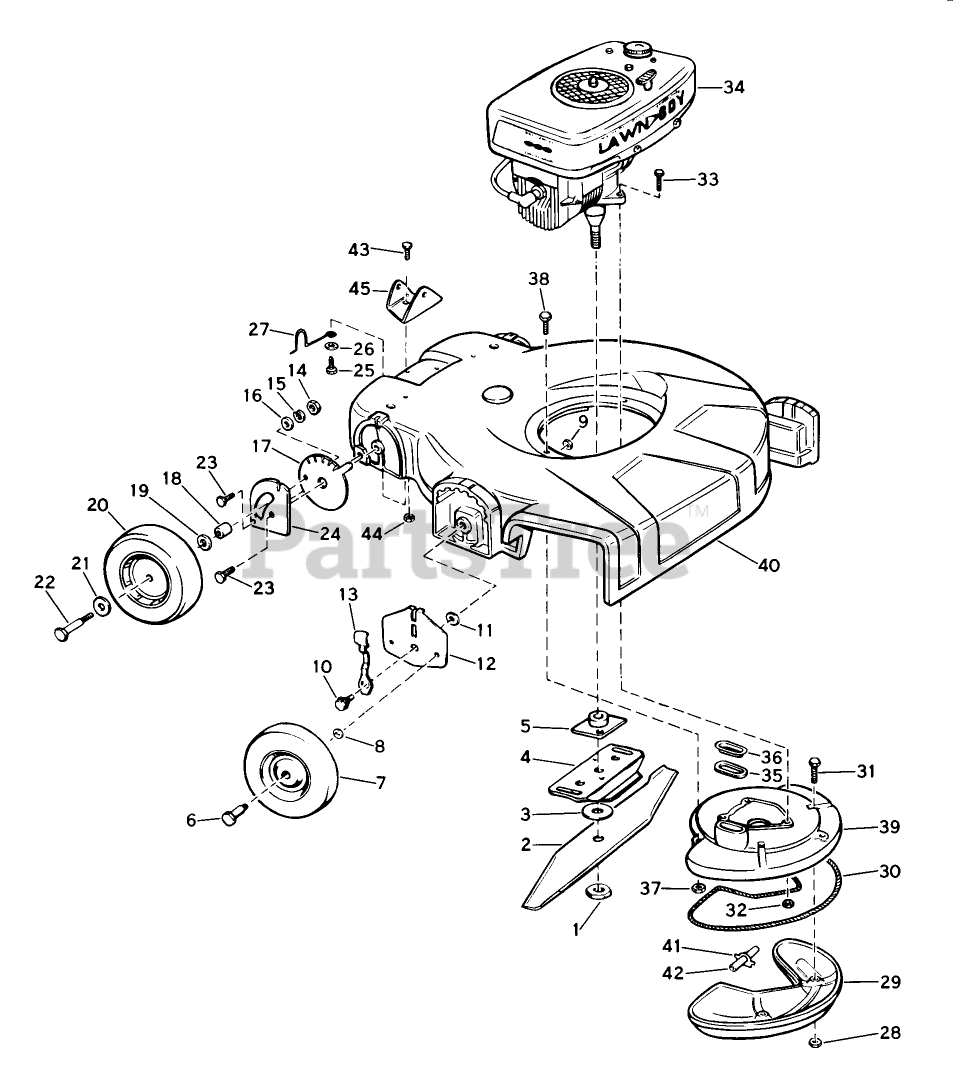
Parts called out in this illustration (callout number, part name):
1	NUT-BLADE
5	PLATE AND COLLAR ASM
6	BOLT WHEEL
8	WASHER WROUGHT
14	Nut-Hex
15	WASHER, LOCK
17	Lever-Wheel
18	Spacer-Wheel
22	Bolt-Wheel
24	Plate-Wheel Height Adj.
27	Spring-Wheel Height Adj.
28	LOCKNUT E
41	Gasket-Internal Tube
42	Tube-Internal Muffler
44	STOP NUT
